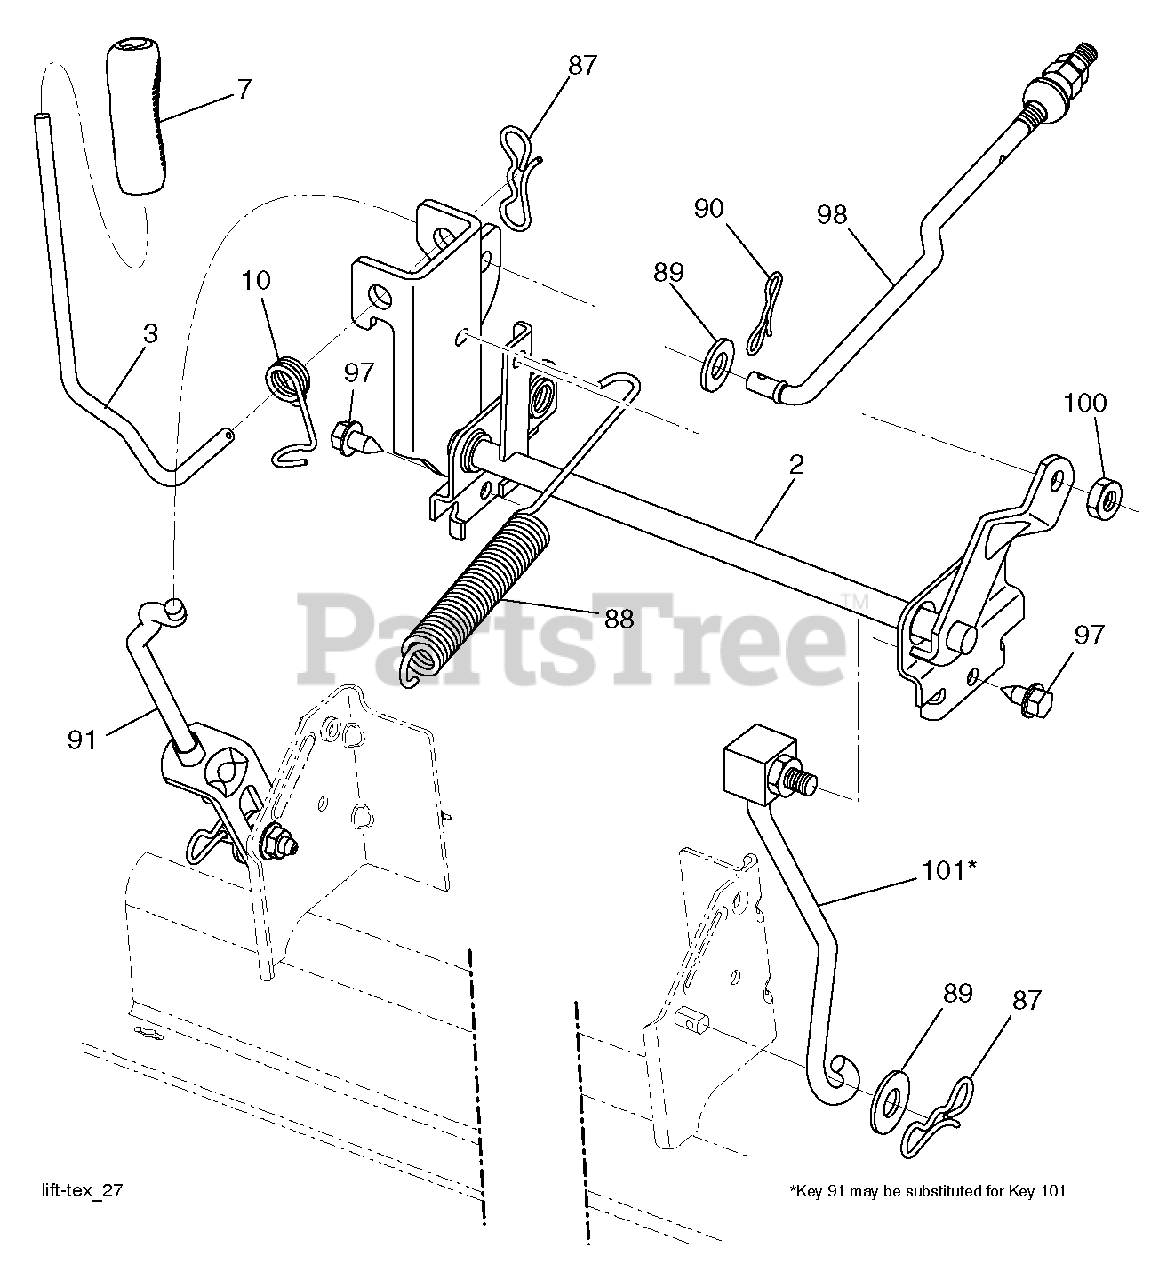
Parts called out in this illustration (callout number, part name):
3	LEVER.LIFT.HANDLE.LT
10	PLUNGER BUT KIT
87	PIN.COTTER.7/16.BOW TI
89	WASHER.CLEAR.ZINC
90	PIN.COTTER.5/16.BOW TI
91	LINK.ASM.LIFT.REAR
98	LINK.ASM.SUSP.FRONT.MW
100	LOCKNUT
101	LINK.ASM.LIFT.FIXE.38/42/46"
